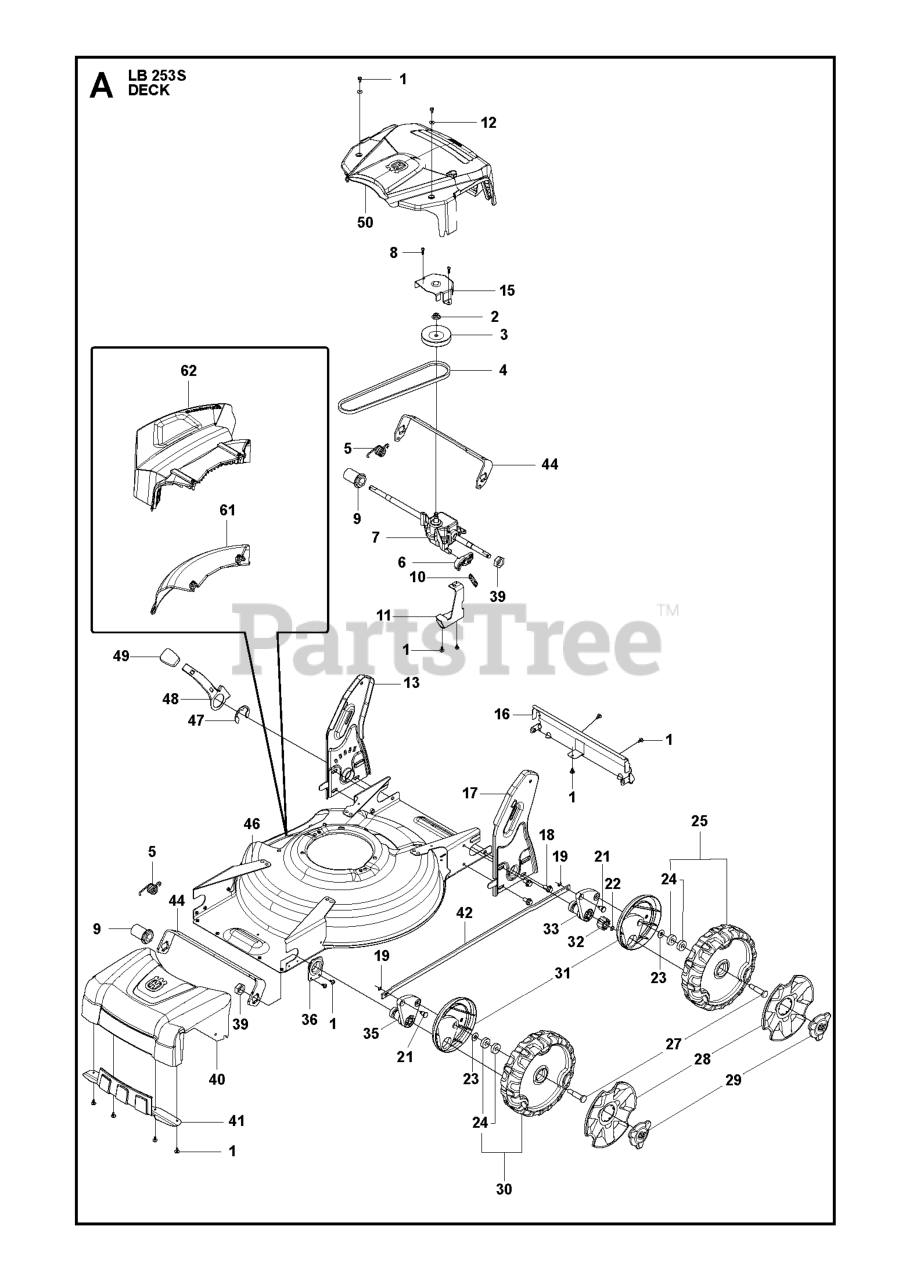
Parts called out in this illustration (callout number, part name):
1	SCREW ITXPANTT M5X10 ZPB (A00
4	BELT WRAPPED V-BELT Z 31 3/4"
8	SCREW ITXPANT T50X16 ZN/FE (A
19	FASTENER
24	BALL BEARING
30	WHEEL ASSY 210, IDLE, MEDIUM
